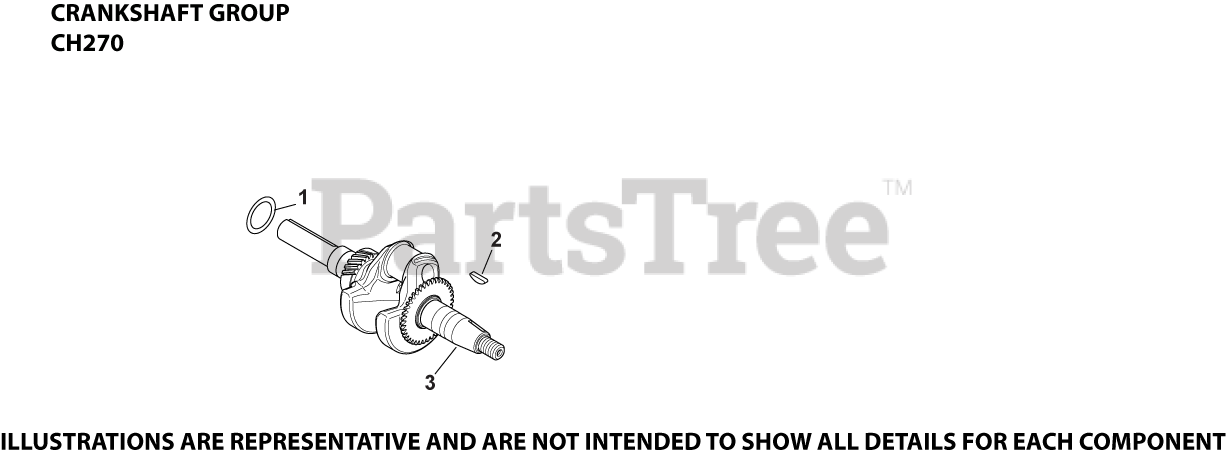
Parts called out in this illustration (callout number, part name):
1	KIT, THRUST SHIM
2	KEY, FLYWHEEL
3	CRANKSHAFT ASSEMBLY
